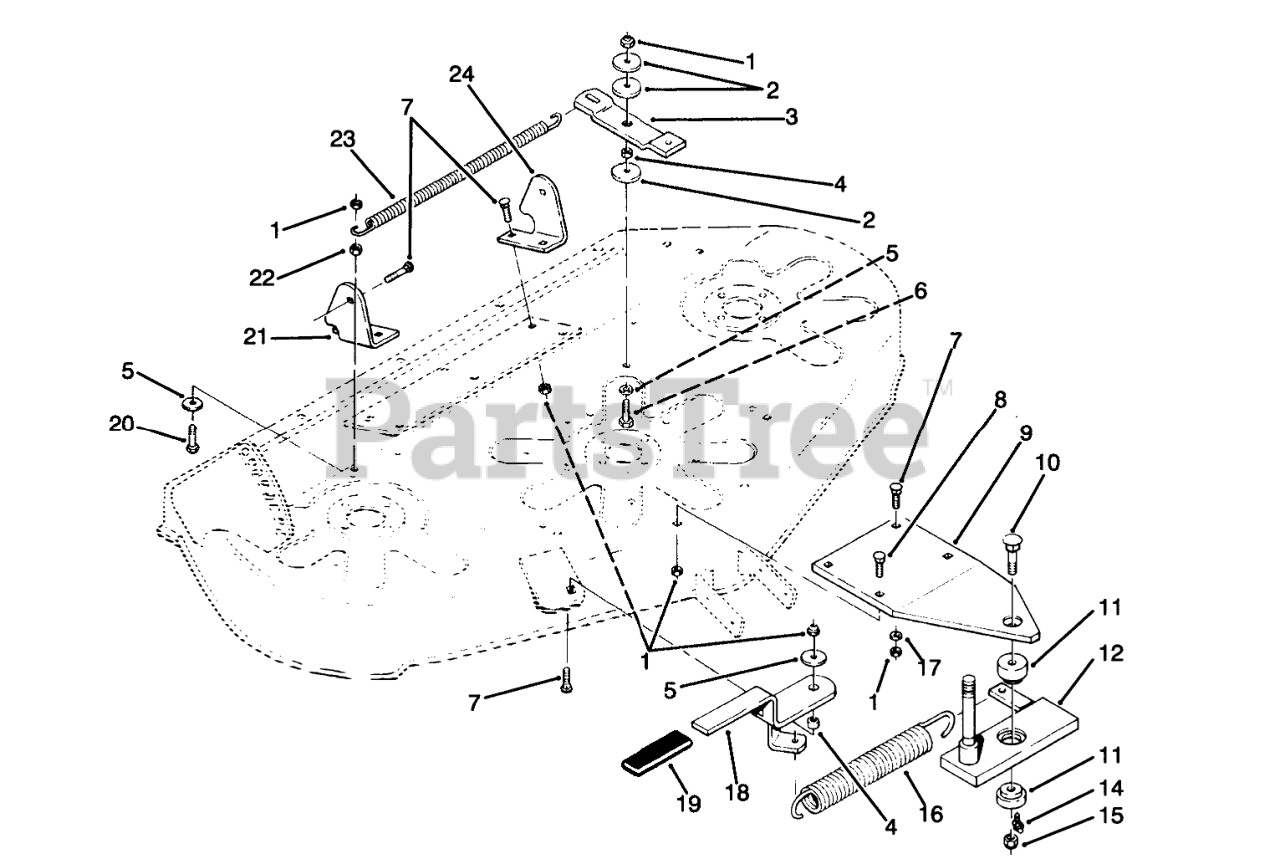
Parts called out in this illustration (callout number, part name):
1	NUT-LOCK, NI
2	Washer
3	Arm-Idler
4	SPACER
5	WASHER
6	SCREW-HH
7	BOLT-CARR
8	BOLT-CARR
9	Plate
10	SCREW-CARR
11	BUSHING
12	Countershaft
14	Fitting-Grease
15	NUT-LOCK, NI
16	Spring
17	Washer
18	Lever
20	SCREW-HH
21	Bracket RH
22	NUT-HEX
23	SPRING - EXTENSION
24	Bracket LH
